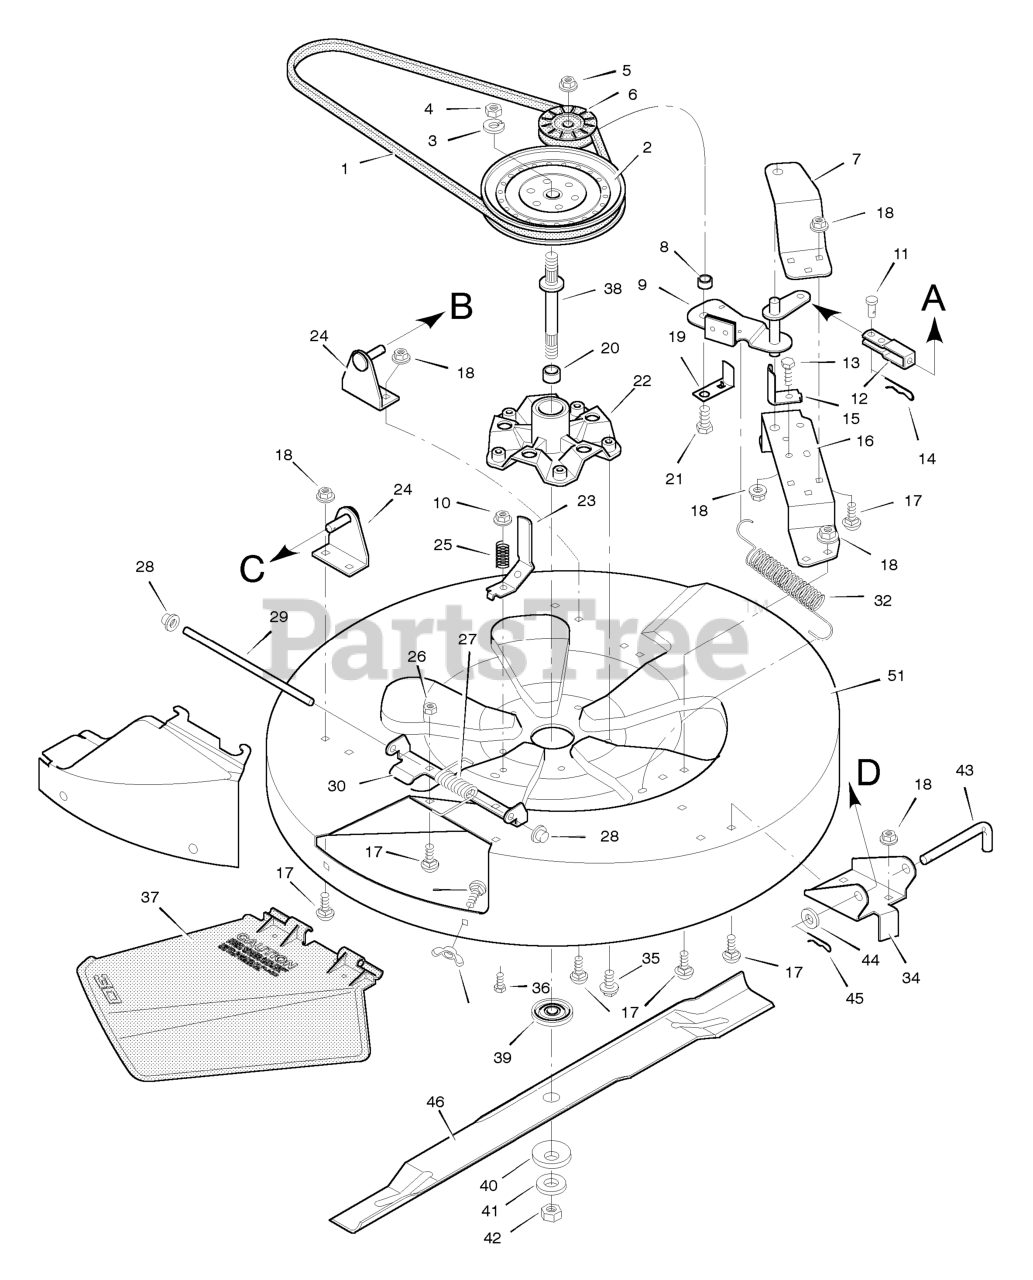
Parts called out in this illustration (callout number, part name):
1	Belt, Mower Drive
2	Pulley, Splined
3	Lockwasher
4	Locknut, Hex
5	Nut, Hex
6	Pulley, Idler
7	Bracket, Upper Idler
9	Assembly, Blade Idler
10	Locknut, Flange
11	Pin, Clevis
13	Bolt, Hex
14	Pin, Hair
15	Guide, Belt
16	Bracket, Lower Idler
17	Bolt, Carriage
18	Nut, Flange
19	Guide, Belt
21	Bolt, Hex
22	Housing, Mandrel
23	Guide, Belt
24	Bracket, Hanger
25	Spring, Compression
26	Nut, Hex
27	Spring - Torsional
28	Push On Cap
30	Hinge, Chute Deflector
32	Spring, Extension
34	Bracket, Front
36	Bolt, Hex
37	Deflector, Chute
38	Mandrel
39	Adapter, Blade
40	Washer, Belleville
41	Washer, Hardened
42	Nut, Hex
43	Pin, Pull
45	Pin, Hair
46	Blade, Standard
47	Blade, Mulcher
48	Plate, Mulcher
49	Bolt, Carriage
50	Wingnut
51	Mower Housing, Complete
